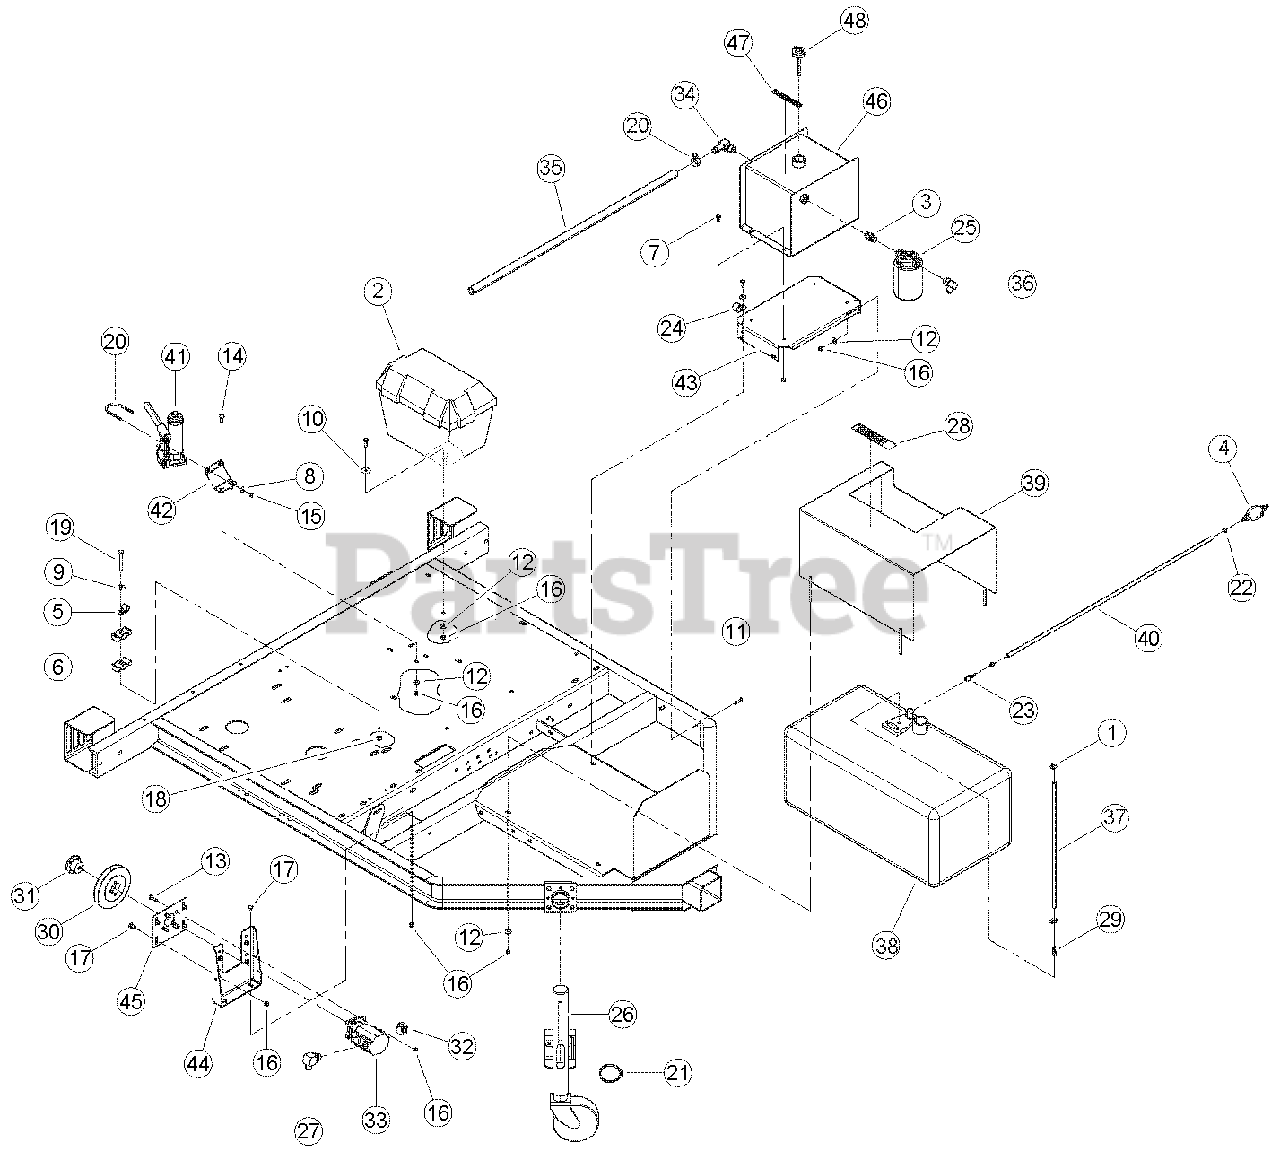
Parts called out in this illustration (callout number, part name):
1	CLAMP, HOSE 5/16 X 5/8 DIA. MAX.
2	BOX, PLASTIC BATTERY
3	ADAPTER, -8 MORING / -8 MJIC
4	BULB, PRIMER
5	CLAMP, 9/16 COATED
6	CLAMP, PLASTIC OSE
7	BOLT, 5/16 X 3/4 HEX HD GR5 ZP
8	WASHER, 1/4 FLAT ZP
9	WASHER, 3/8 FLAT ZP
10	WASHER, 5/16 FENDER ZP
11	BOLT, 5/16 X 1 HHCS GR5 NC ZP
12	WASHER, 5/16 FLAT ZP
13	BOLT, 5/16 X 1 CRG GR5 ZP
14	BOLT, 5/16 X 7/98CRG GR5 NC ZP
15	NUT, 1/4 NE NYLOCK ZP
16	NUT, 5/16 NE NYLOCK ZP
17	BOLT, 5/16 X 3/4 CRG GR5 NC ZP
18	NUT, 3/8 NE NYLOCK ZP
19	BOLT, 3/8 X 2-3/4 HHCS GR5 NC ZP
20	U-BOLT, 1/4 X 1-1/2 PIPE
21	SNAP RING, 2-1/2 EXTERNAL
22	CLAMP, 15/32 SPRING
23	FITTING, 1/4 NPT. X 1/4 HOSE
24	CLAMP, 1 IN. COATED METAL
25	FILTER, SPIN-ON
26	JACK, PIVOTING W/SWIVEL CASTOR
27	ADAPTER, -10 MORING / -10 MJIC 90 DEG.
28	DECAL, DIESEL FUEL
29	FITTING, 1/8 MNPT X 1/4 HOSE
30	SHEAVE, QT 1B5.6
31	BUSHING, QT 1/2
32	CLAMP, 1-5/32 TO 7/32 OD RANGE T-BOLT
33	PUMP, 2 STAGE CW HI/LO 0.605 DISP.
34	ADAPTER, -10 MORING / .75 90 DEG. HOSE
35	HOSE, .75 ID. X 38 IN. 100R4 HYD.
36	ADAPTER, -8 MORING / -8 MJIC 90 DEG.
37	HOSE, 76 IN. FUEL RETURN
38	TANK, DIESEL FUEL
39	WELDMENT, FUEL TANK CLAMP
40	HOSE, 38 IN. FUEL LINE
41	JACK, HYDRAULIC 2 TON
42	PLATE, JACK MOUNT
43	SHEET, TANK MOUNT
44	BRACKET, MOUNT HYDRAULIC PUMP
45	PLATE, PUMP MOUNT
46	ASSEMBLY, HYD. TANK 3.25 GAL, SERVICE PART
47	DECAL, HYDRAULIC FLUID
48	CAP, W/DIPSTICK
48	PLATE, PUMP MOUNT
